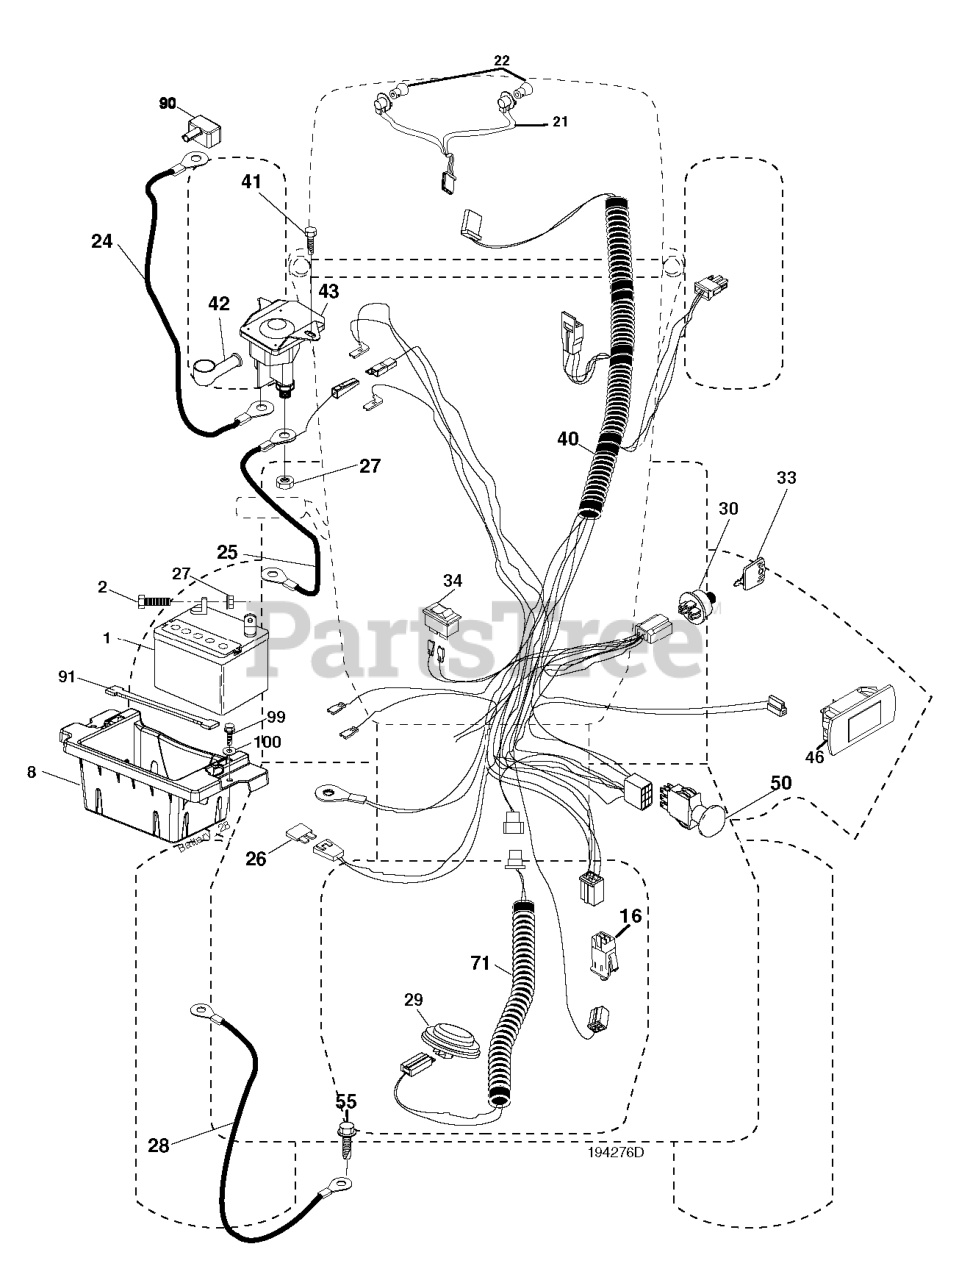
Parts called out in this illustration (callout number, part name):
1	BATTERY 12V .35 AMP
2	BOLT.HEX.1/4.X.3/4.DICHROMATE
8	BOX.BATTERY.MOUNT.FRONT.LT
16	SWITCH INTERLOOK PUSH-IN
21	HARNESS.W/LIGHT SOCKET
24	CABLE.BATT.POS.WIRE.TG.DA SOL
25	CABLE.STARTER.6GA.RED.
26	FUSE 20AMP
27	NUT
28	CABLE GROUND 6 GA 21" 90T BLK
30	SWITCH.IGN.DELTA.W.LGH.ROS
33	KEY MLD GEN DELTA
40	HARNESS-CHASSIS SUB
41	SCREW
42	TERMINAL COVER
43	SOLENOID.W/BRASS.PLUNGER
46	RP.GUAGE.SRVCMNDR.HRMTR.
50	RP.PTO.SWITCH.8 TERMINAL.BLACK
55	SCREW 5/16"
71	HARNESS.IGN.DASH.HUQ/P
90	COVER.TERMINAL.BATTERY
91	STRAP.BATTERY.MOUNT.FRONT(2 2)
99	SCREW HEXWSHR 1/4-20X3/4
